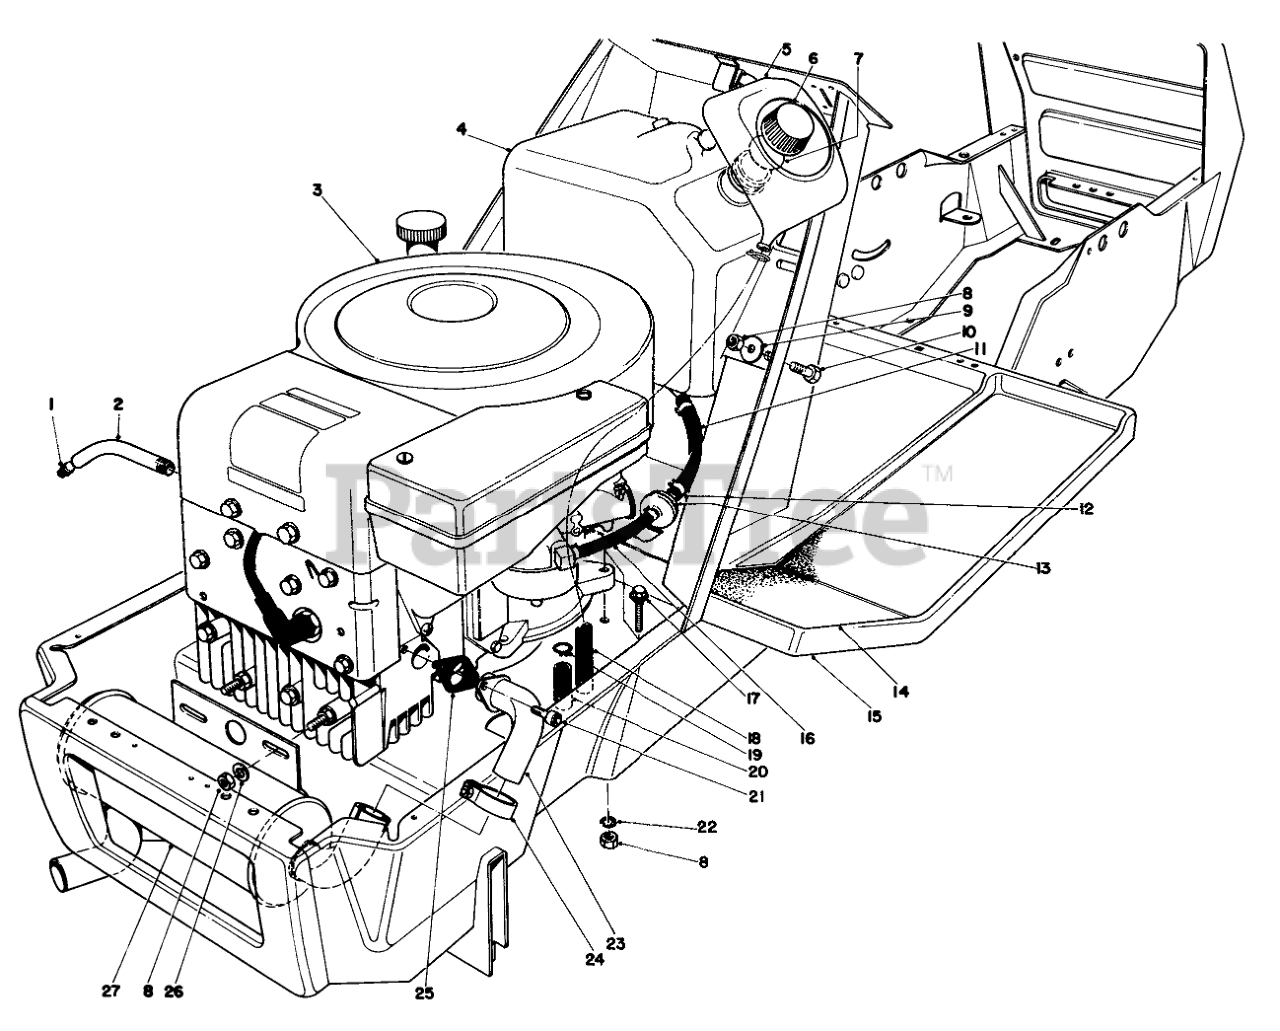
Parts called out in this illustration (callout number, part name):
1	PLUG-PIPE, SQH
2	OIL DRAIN TUBE
3	Engine
4	Gas Tank (Incl. Ref. #5)
5	Funnel-Overflow
6	Gas Cap (Incl. Ref. #7)
7	Gasket Gas Cap
8	NUT-LOCK, CONE
9	WASHER
10	SCREW-HH
11	HOSE-FUEL
12	FUEL HOSE CLAMP
13	Nut
14	LH FOOT TREAD
15	Frame
16	GAS HOSE
17	SCREW-HH
18	FUNNEL HOSE
19	HOSE CLAMP
20	Hose-Carburetor Drain
21	SCREW-HSH
22	WASHER-LOCK, INTERNAL
23	Exhaust Pipe
24	Clamp-Exhaust Pipe
25	Exhaust Gasket
26	WASHER-PLAIN
27	MUFFLER
